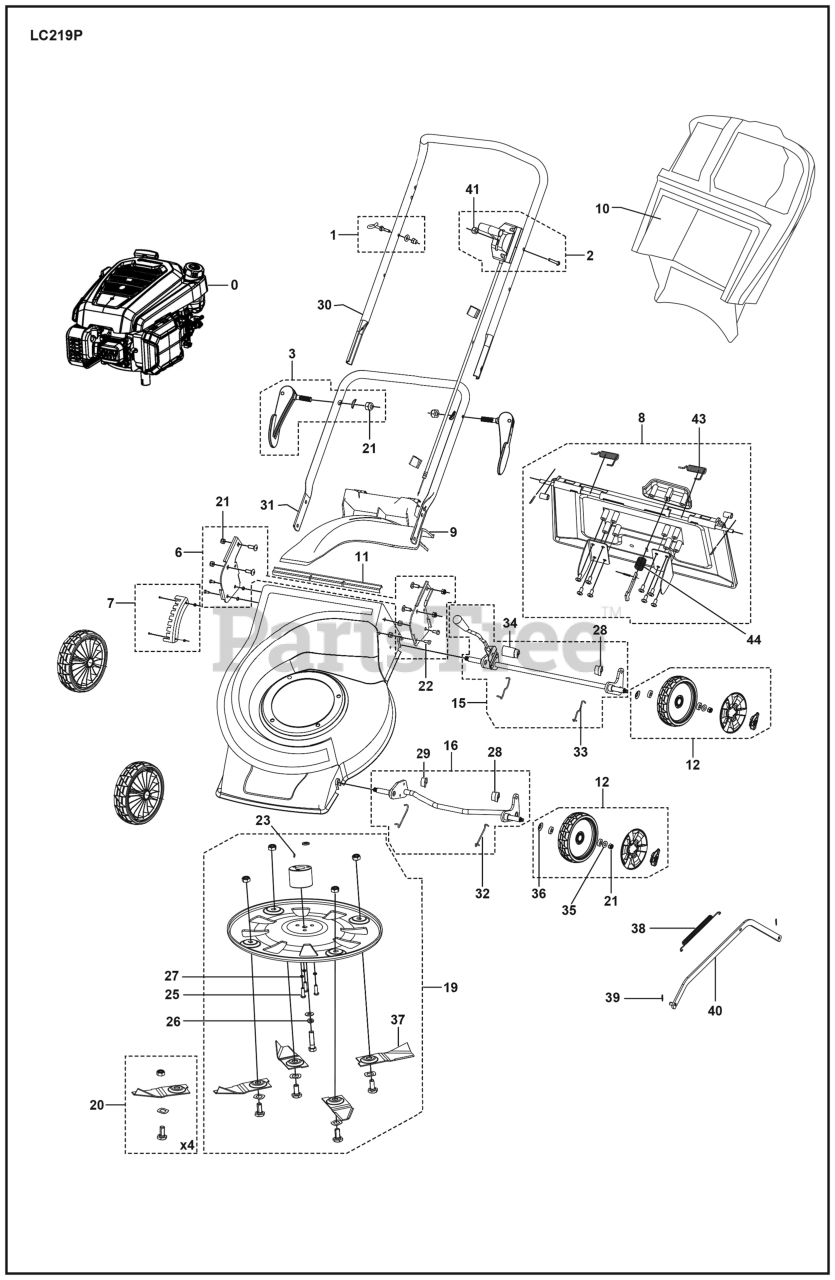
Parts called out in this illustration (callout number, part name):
21	LOCKNUT M8
22	BOLT - M8X16
26	Spring Washer
27	WASHER SPRING LOCK WASHER WITH
41	LOCKNUT M6
